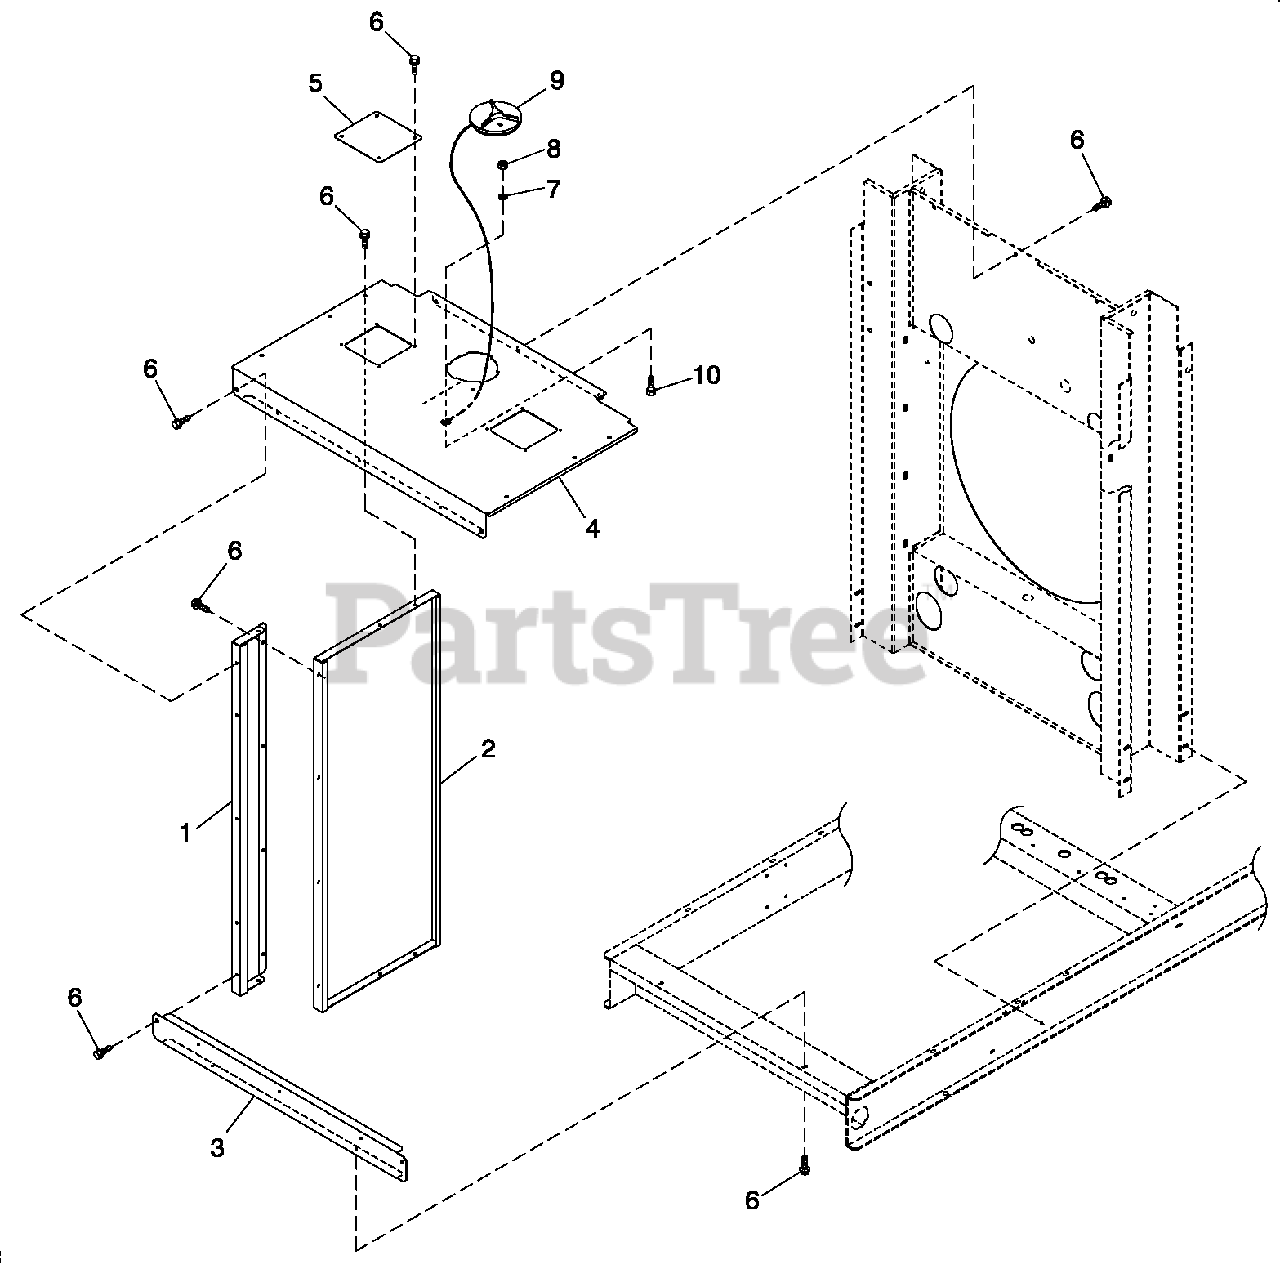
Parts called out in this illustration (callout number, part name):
1	PANEL C3 FRONT SIDES
2	PANEL C3 REAR SIDES
3	PANEL LOWER FRONT
4	PANEL C3 TOP
5	ACCESS COVER 160 X 170 GALV
6	SCREW THF M6-1 X 16 N WA Z/JS
7	WASHER LOCK M6-1/4
8	NUT HEX M 6X 1.0 G8Y E LC H R
9	ASSY ACCESS COVER
10	SCREW HHC M6-1.0X 16 G8.8
